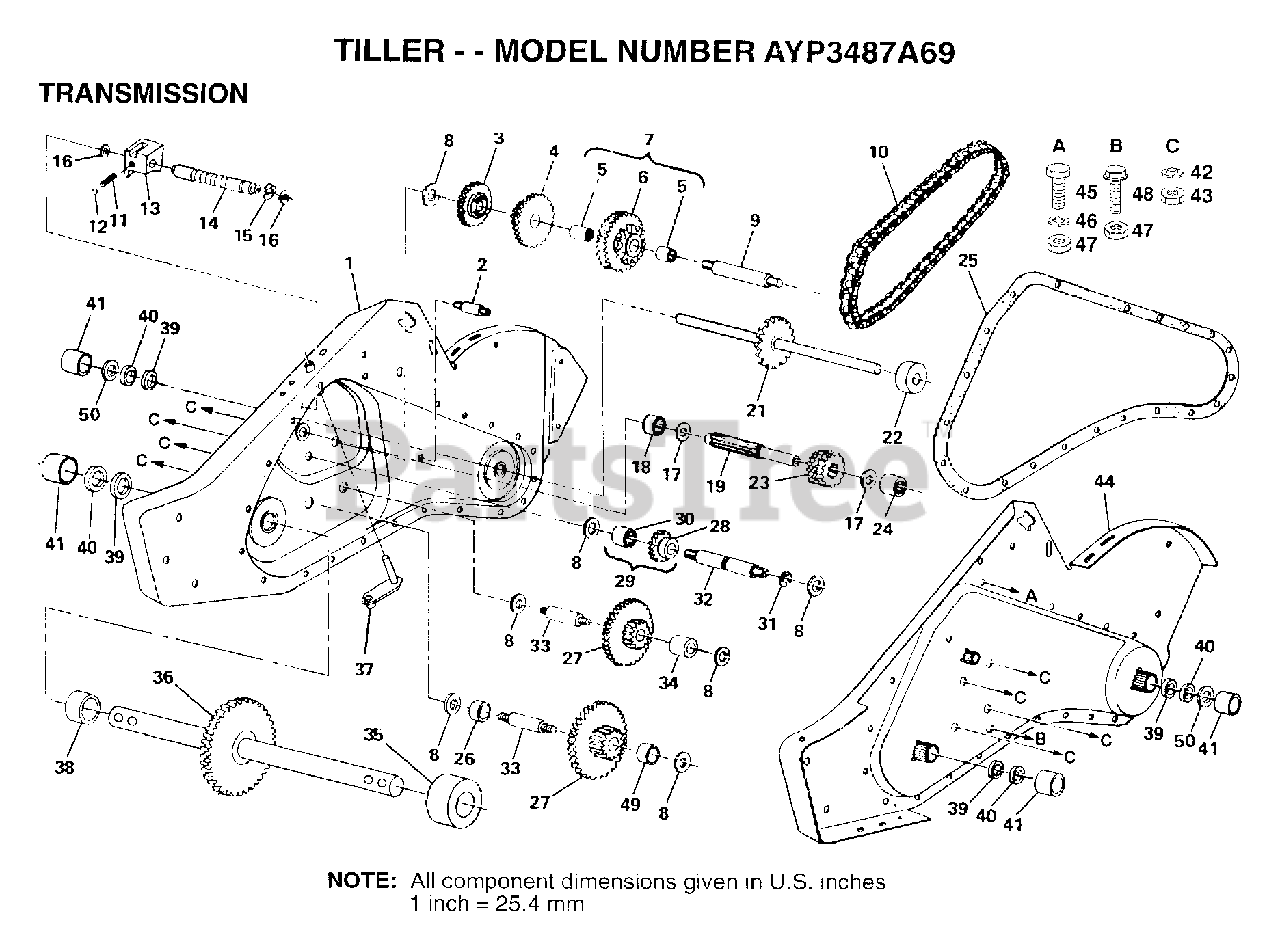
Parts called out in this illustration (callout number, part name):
2	BOLT TI
3	REVERSE GEAR TI
4	CLUSTER GEAR TI
5	"CRT, BEARING"
7	SPROCKET ASSY TI
8	WASHER
9	REDUCTION SHFT TI
10	CHAIN TI
11	SPRING-SHIFT CRT
13	SHIFT FORK TI
14	SHIFT SHAFT TI
15	KLIP RING
16	WASHER SEAL CRT
17	"T, BEARING"
18	"TI, BEARING"
19	SHAFT INPUT
21	SHAFT TINE CRT
22	SPACER CRT
23	INPUT PINION TI
24	NEEDLE BRNG LT
25	GEARCASE GSKT TI
26	SPACER CRT
27	GEAR CLUSTER CRT
28	REVERSE GEAR TI
29	GEAR ASSY TI
30	NEEDLE BEARING TI
31	KLIP RING
32	REVERSE SHAFT TI
33	SHAFT CRT
34	SPACER CRT
35	SPACER CRT
36	SHAFT ASSY CRT
37	BRACKET ASM SHIFT
38	SPACER CRT
39	OIL SEAL STD
40	SEAL RING RUBBER
41	CUP.FORMED.
42	LOCKWASHER
43	NUT.ASF.HEX.7/16
45	SCREW 5/16-18X5/8
47	NUT.HEX.5/16-18
48	BOLT TI
49	SPACER CRT
50	RING SPIRAL CRT
